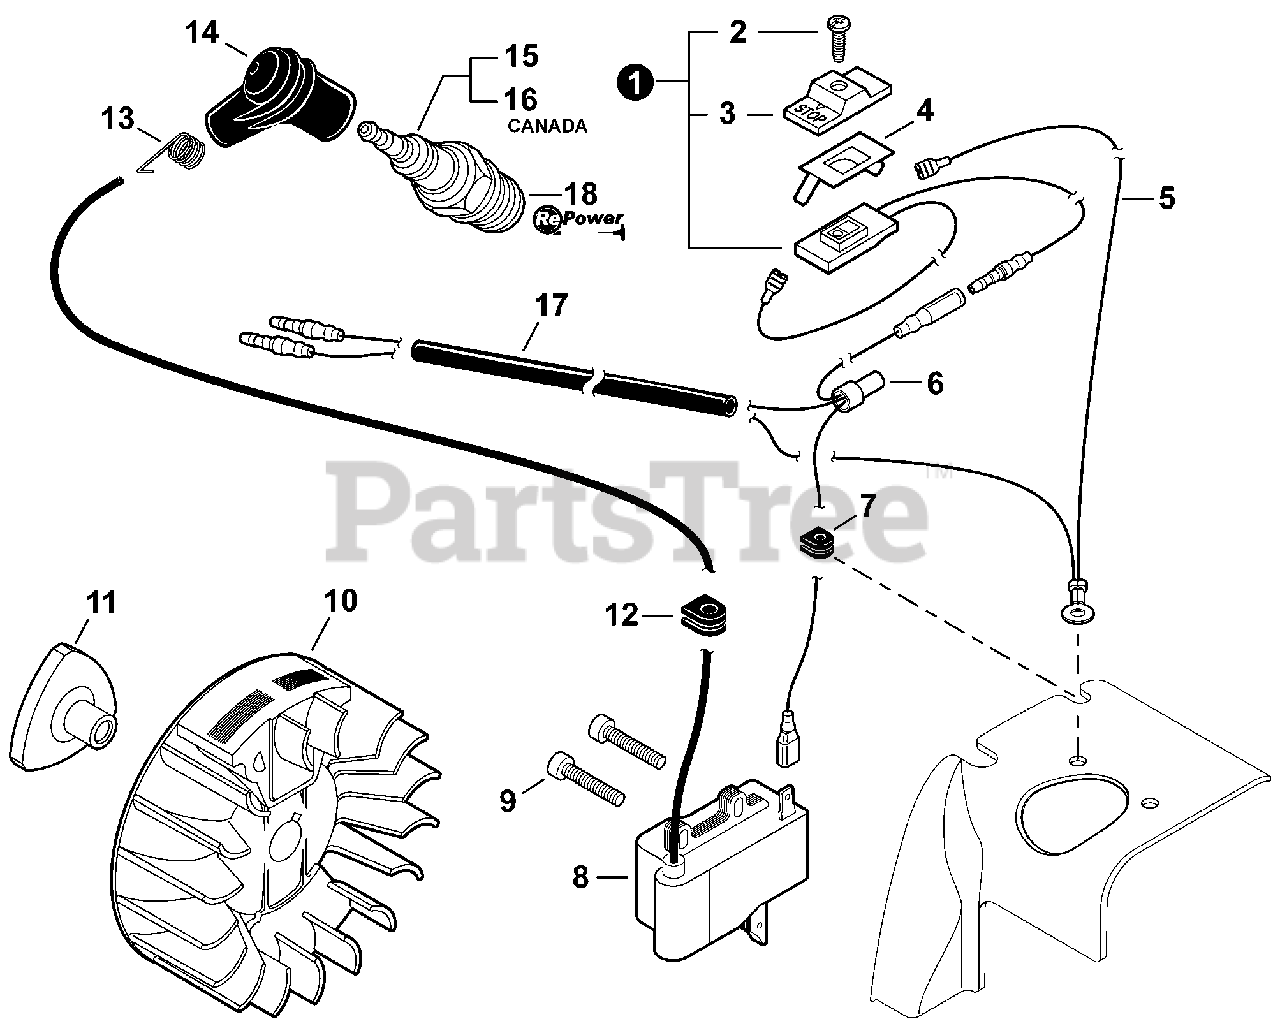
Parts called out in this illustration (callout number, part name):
1	SWITCH ASSY, ON-OFF
2	SCREW 3×10
3	KNOB, SWITCH - ORANGE
4	TERMINAL, LEAD
8	COIL, IGNITION
9	BOLT, TORX 4×20
10	FLYWHEEL
11	HUB, FAN
13	TERMINAL, SPARK PLUG
14	CAP, SPARK PLUG
15	SPARK PLUG - BPM8Y
16	SPARK PLUG - BPMR8Y
17	TUBE, INSULATOR
18	TUNE-UP KIT - REPOWER
